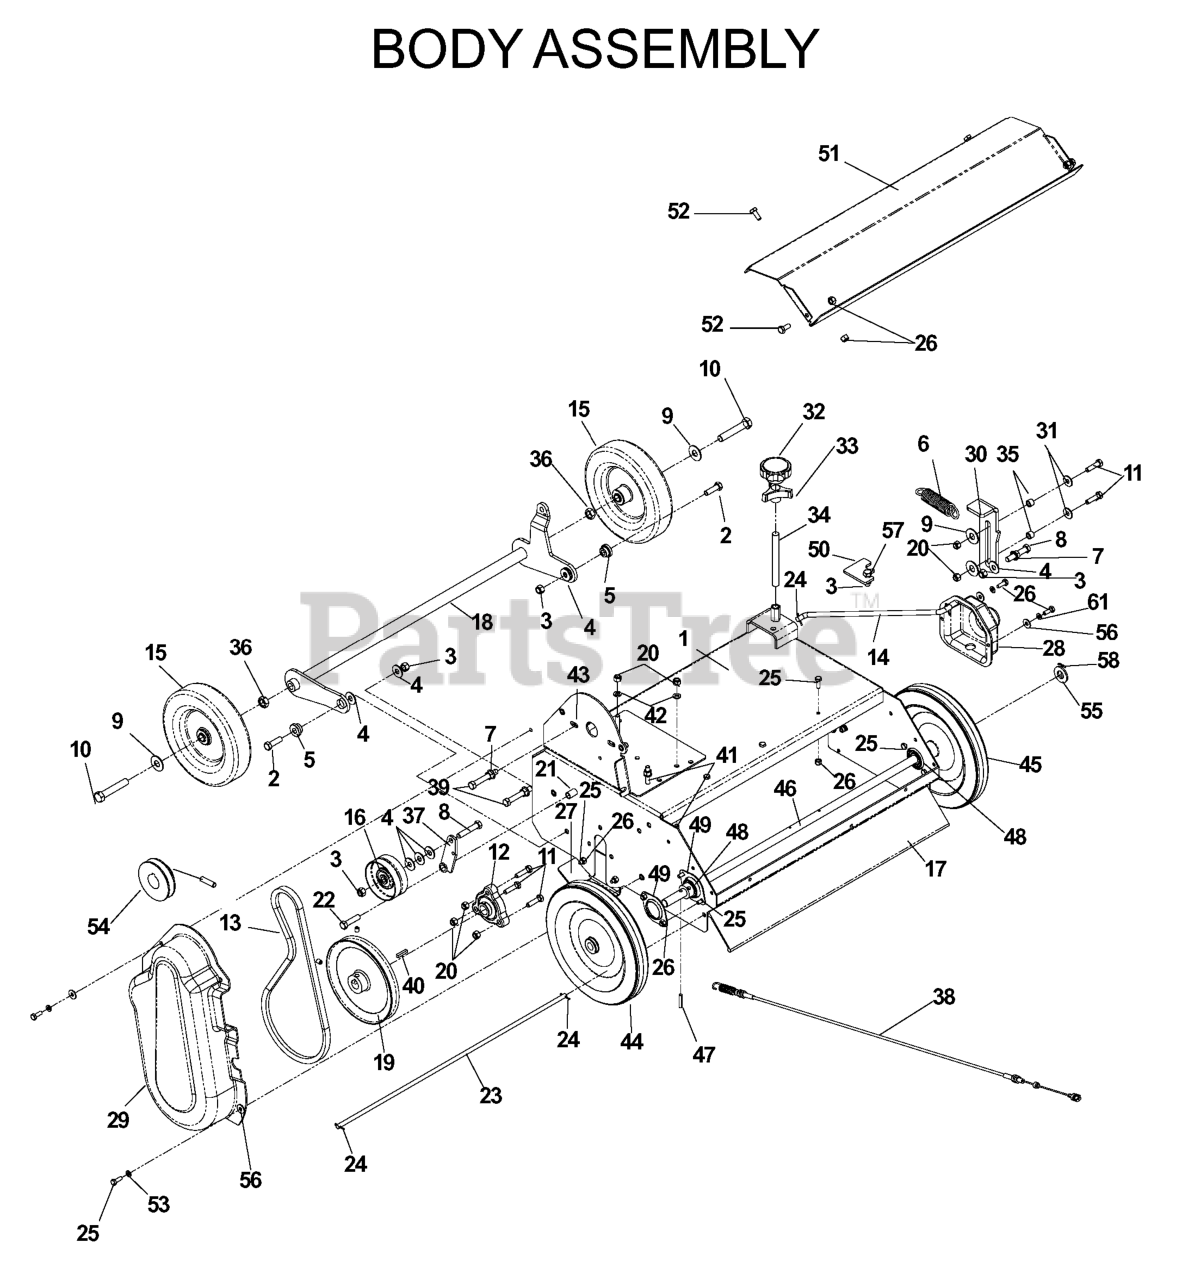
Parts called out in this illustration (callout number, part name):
1	BODY W/DECALS
2	HCS 3/8C X 1 1/4 GR5
3	NUT 3/8-16 NYLOC
4	WASHER 3/8 FLAT
5	BUSHING RAKE
8	HCS 3/8C X 2
9	WASHER 1/2 FLAT
10	HCS 1/2C X 2 3/4
11	HCS 5/16C X 1 1/4
12	BEARING, FLANGED
13	BELT, DRIVE RAKE/SLICER DFS
15	WHEEL 8 X 1 3/4 RAKE
16	PULLEY, IDLER 3 1/4 OD PAINTED
18	FRONT AXLE
19	PULLEY W/SET SCREW
20	NUT 5/16 NYLOC
21	BEARING, ONLITE RAKE/DT
22	HCS 3/8C X 1 1/2
24	COTTER PIN 3/32 X 3/4
25	HCS 1/4C X 3/4 HCS
26	NUT.1/4-20.HEX.NYLOC.ZD
27	SKID PLATE
28	SHAFT GUARD
29	BELT SHIELD POWER RAKE
31	WASHER 5/16 FLAT
34	R/B 108588 STUD, THREADED
36	NUT 1/2 HEX JAM
37	IDLER ARM - ORANGE
38	CABLE POWER RAKE
39	HCS 3/8C X 2 1/2
40	R/B 910061 KEY 3/16 SQ. X 1 LG
41	HCS 5/16C X 1 3/4
42	WASHER.LOCK.HVY.HLCL.SPR.5/16
43	BACKING PLATE ORANGE
44	WHEEL 10 X 1 3/4
45	WHEEL 10 X 1 3/4
46	AXLE, REAR
47	DNB BUSHING STEERING Y
48	BEARING - 5/8" W/COLLAR
49	FLANGE BEARING ZINC PLATED
50	DEPTH SHIM
51	REAR COVER ORANGE
52	HCS 1/4C X 5/8
53	LOCKWASHER 1/4"
54	ENGINE PULLEY W/SET SCW
55	WASHER
56	WASHER 1/4 FLAT
57	HCS 3/8-16X1.GRD.5.ZD
58	COTTER PIN
